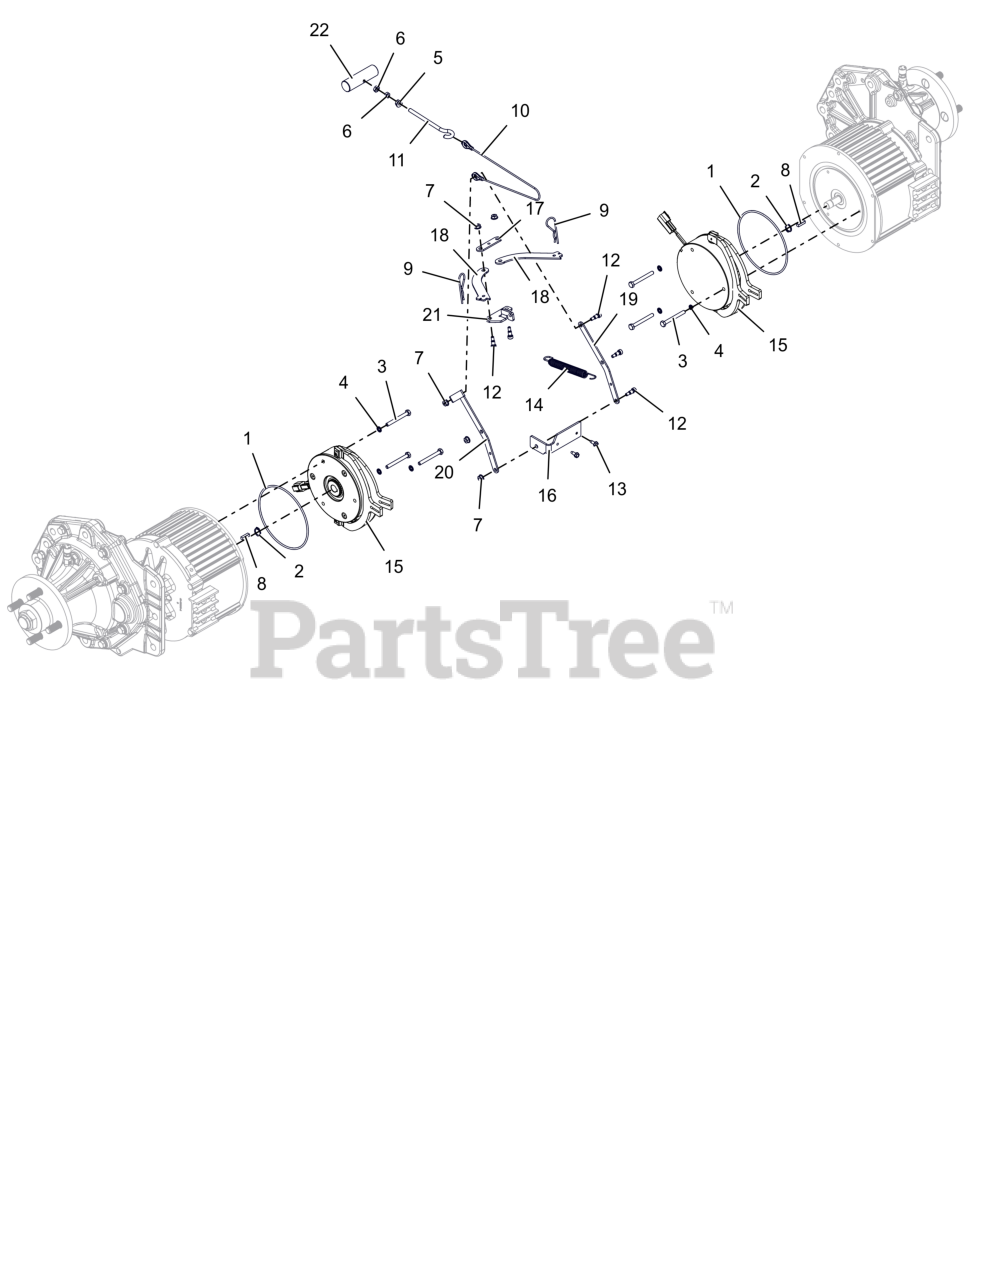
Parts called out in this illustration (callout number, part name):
1	O-RING 126MM IDX3MM
2	RING, RETAINING-EXTERNAL 25MM X 1.2MM
3	BLT,HEX M6-1X55 EP30 G8.8 ZCC
4	WSHR-FL-STL, SEAL 6MMX11MMX1MM
5	NUT-LK-CTR-FLG .25-20 ZC120
6	NUT-JAM .250-20 G2 ZCC
7	NUT, FLG-TOP LK #10-24 GRF ZCC
8	KEY-STR 5X5X18MM RD ENDS
9	PIN, HAIR-#7 .094X2.31 ZC120
10	CABLE, LOWER TRACTION (CMPCT)
11	BOLT, EYE .250-20 x 3.00
12	BLT-SHLDR .25X.375
13	SCR,TAP #10-24X.50 HWH TR ZCC
14	SPRING, SWIVEL HOOK EXTENSION
15	BRAKE, MOTOR
16	PIVOT, BRAKE LINK MAIN
17	PLATE, BRAKE PULL DOUBLER
18	LINK- PUSH
19	LINK MIDDLE
20	LINK- MIDDLE
22	HANDLE- BRAKE
